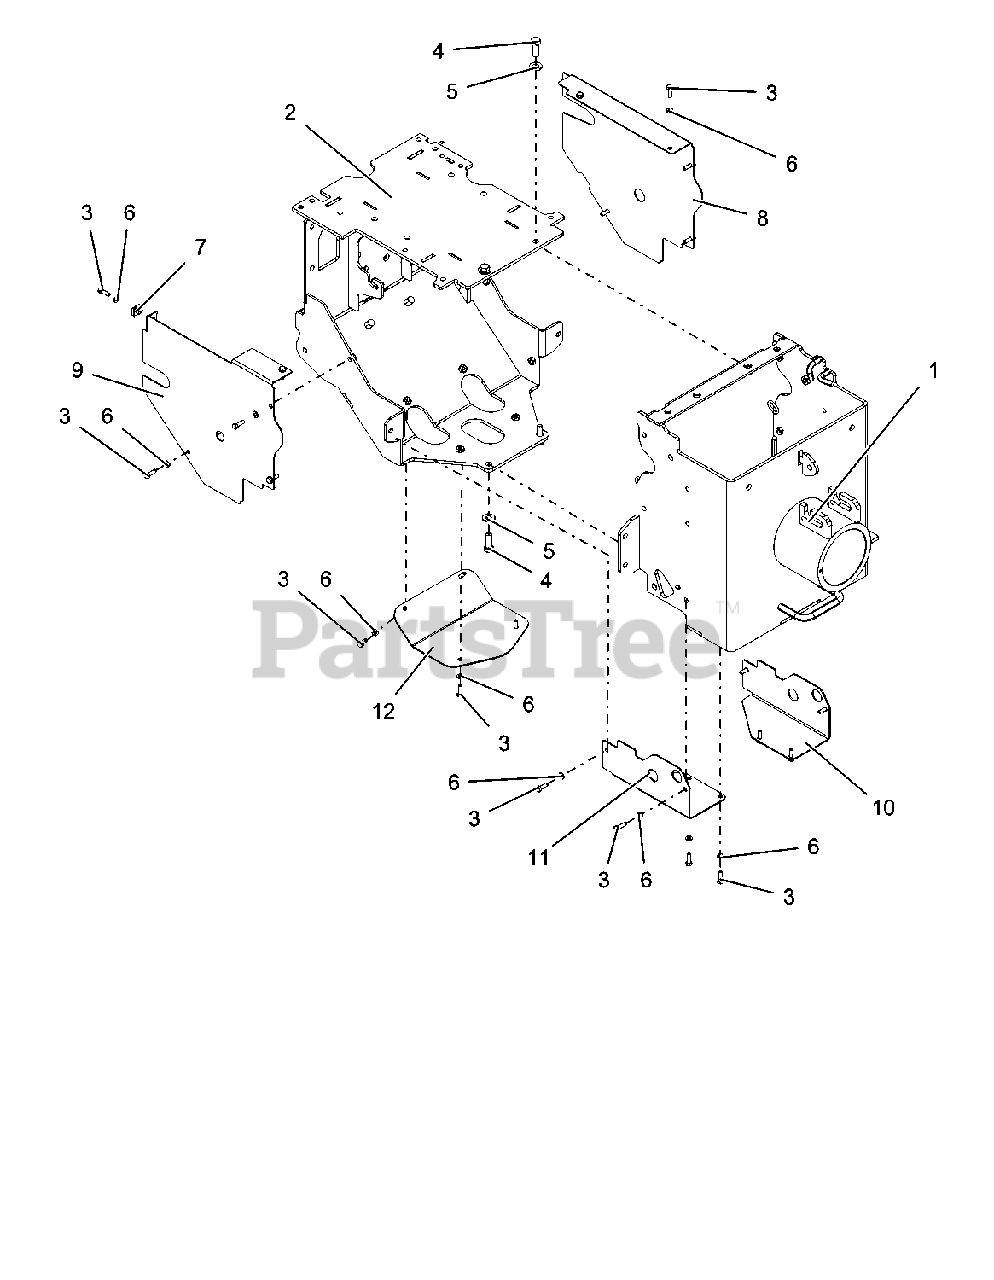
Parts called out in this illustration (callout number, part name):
1	WLDMT, FRONT HOUSING-RED
2	WLDMT, FRAME BACK-RED
3	BLT, HEX M6-1X20 GR8.8 ZC120
4	BLT, HEX M10-1.5X30 GR8.8 ZC120
5	WSHR, 3/8" SPRING DISC
6	WSHR-LK .25X.062 REG YWZC
7	NUT, RTNR M6 X 1.0
8	COVER, LH-RED
9	COVER, RH-RED
10	COVER, LH LOWER-RED
11	COVER, RH LOWER-RED
12	COVER, OIL-RED
